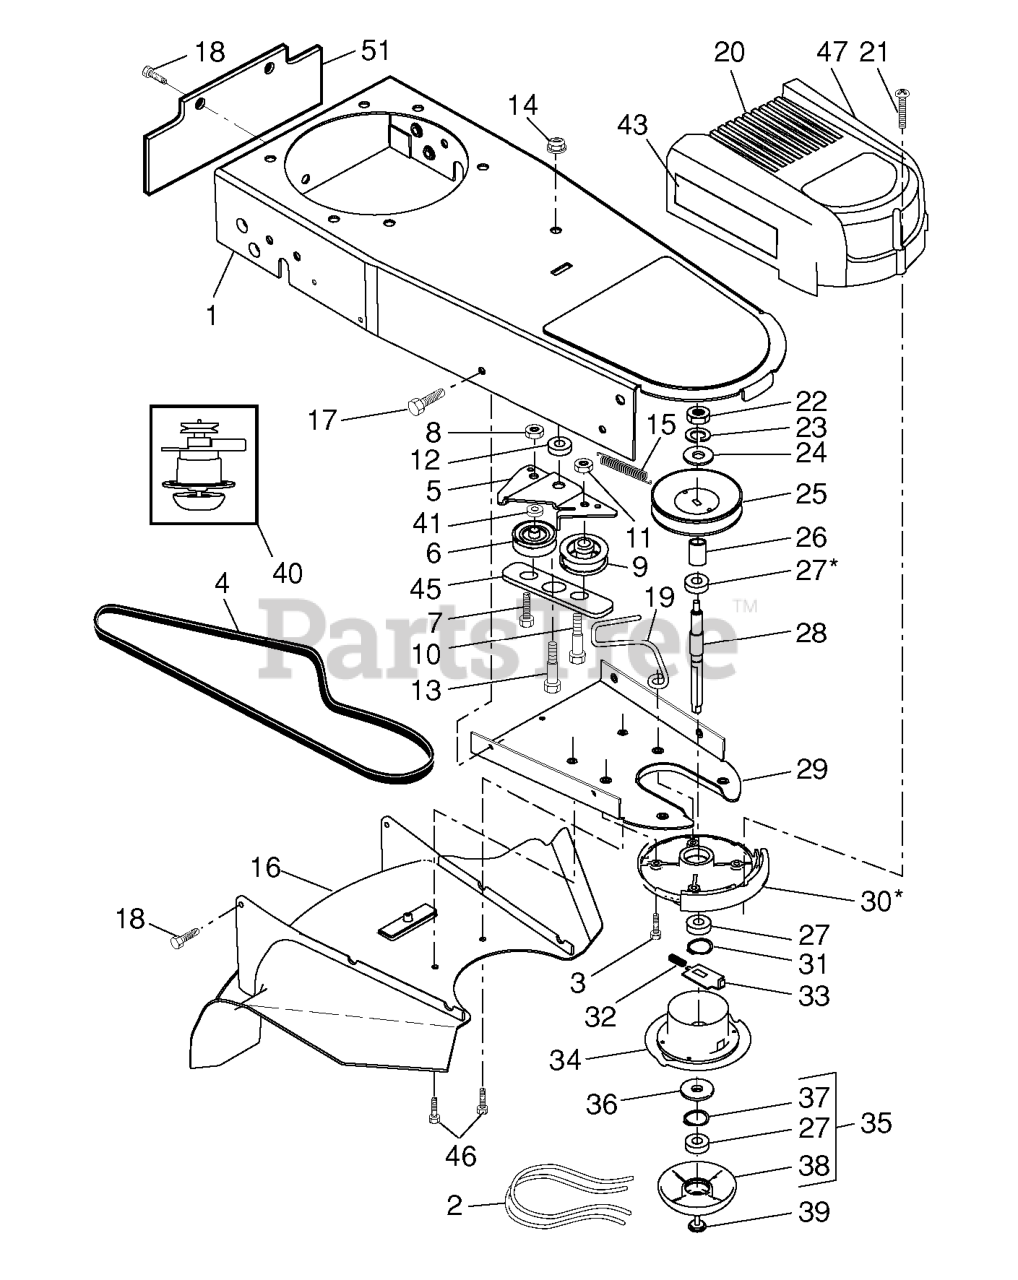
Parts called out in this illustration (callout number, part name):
1	HOUSING.CHASSIS ASM.MID.ORANGE
2	LINE.BUND.18PC
3	BOLT.HEX.HDWSH.5/16-18X1.00
4	BELT-V.STRING TRIMMER.
5	RP.BRACKET.IDLER.TRIMMER.WHEEL
6	PULLEY.V-GROOVE.IDLER
7	BOLT, HEX HEAD 3/8-16 X 1.25
8	LOCKNUT
9	IDLER PULLEY
10	SHOULDER BOLT
11	NUT.CENTERLOCK.5/16-
12	SPACER.IDLER.BRACKET
13	BOLT SHOULDER 3/8 -16X1
14	NUT.HEX.FLANGE.3/8-16.LOCKNUT
15	SPRING.RETURN.WHEELED.TRIMMER
16	DEFLECTOR, BOTTOM
17	SCREW 14-20 X 5/8
19	KEEPER.BELT.STRING.TRIMMER
20	COVER.SUBASM.COVER/IMD.HUSQ
21	SCREW.SLOT.TORX.
22	NUT
23	LOCKWASHER
24	WASHER, FLAT 3/8
25	PULLEY.SPINDLE.WHEELED.TRIMMER
26	SPACER, PULLEY
27	BEARING
28	JACKSHAFT.WHEELED.TRIMMER
29	CHASSIS.COVER.BOTTOM.BLACK
30	SPINDLE HOUSING ASSEMBLY
31	RING, RETAINING, EXTERNAL,
32	SPRING.1.5".COMPRESSION
33	PLATE.LOCKING.WHEELED.TRIMMER
34	CARRIER PLATE ASSEMBLY
35	MOW BALL ASSEMBLY
36	COVER, BEARING
37	RING, RETAINING, INTERNAL,
38	MOW BALL
39	BOLT, MOW BALL
40	ASM.ADJUSTABLE.SPINDLE.WHLD.TR
41	SPACER (2 2MC)
43	DECAL.TRIMMER.WHEELED.INSTRUCT
45	BRACKET.BELT.KEEPER.BLACK
47	DECAL.TRIMMER.WHEELED.HEIGHT
51	SKIRT.REAR.WHEELED.TRIMME(3 2)
